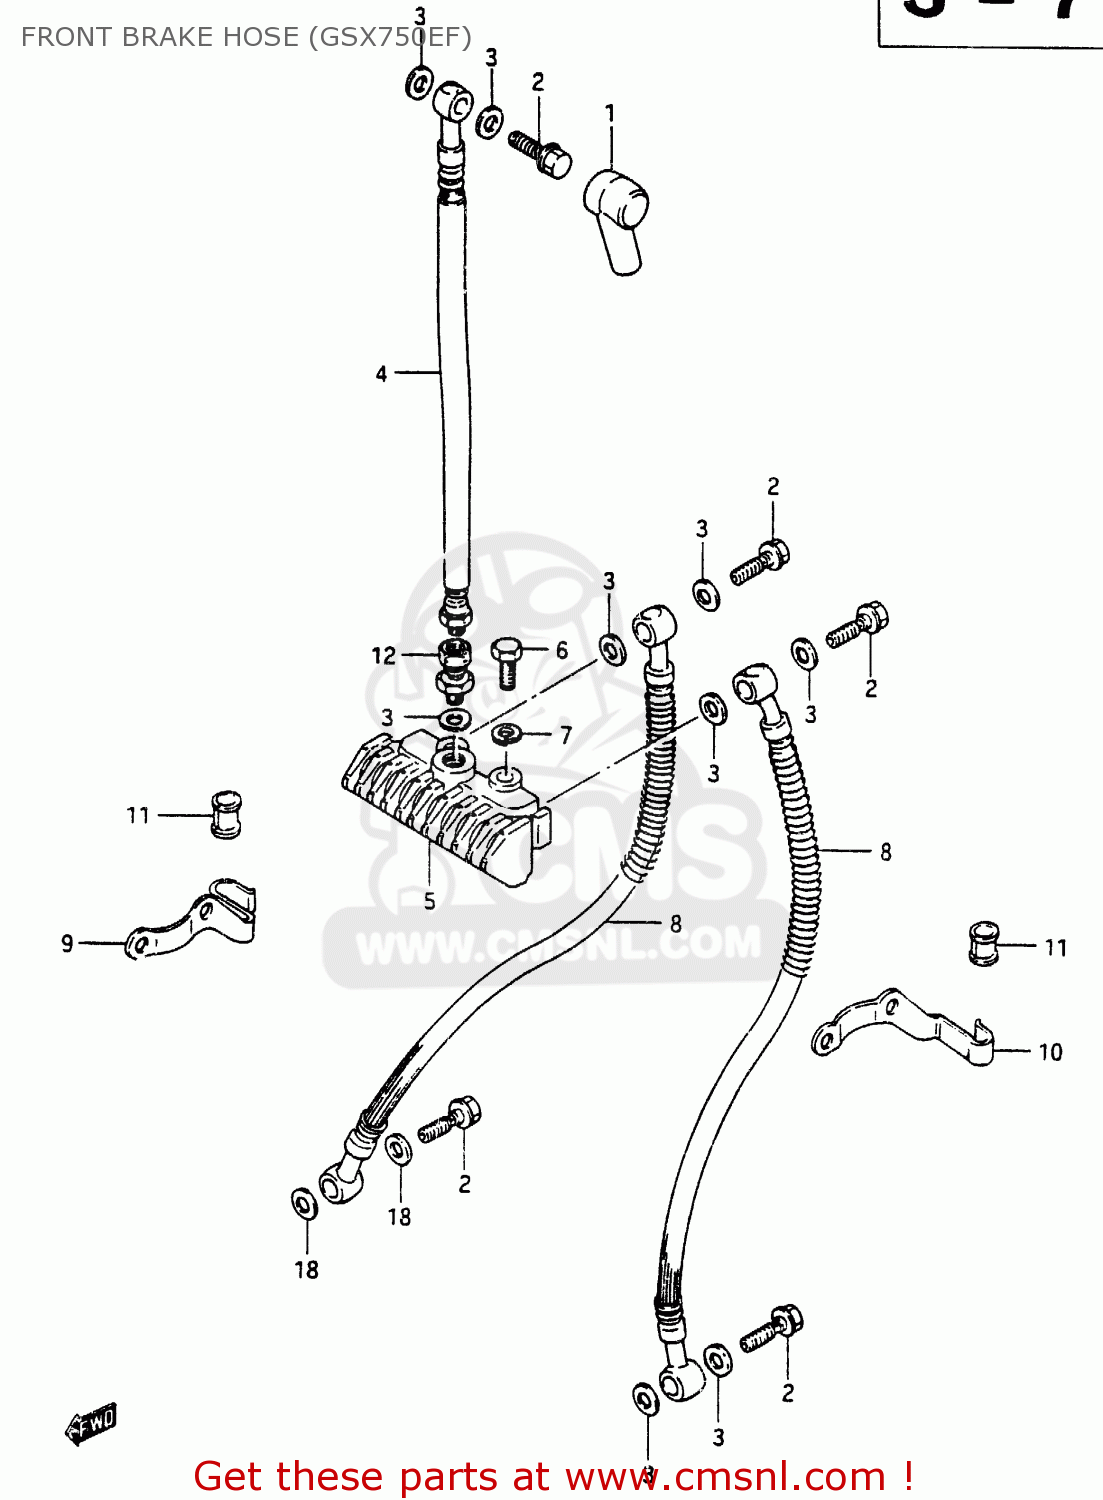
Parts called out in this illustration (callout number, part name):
1	BOOT
2	BOLT UNION
3	WASHER(10X15X1.5)
4	HOSE,FRONT BRAKE NO.1
5	JOINT,BRAKE HOSE
6	BOLT
7	LOCK WASHER
8	HOSE,FRONT BRAKE
9	CLAMP, HOSE RH
10	CLAMP,FRONT BRAKE HOSE
11	BUSH,BRAKE HOSE GUIDE,NO.2
12	ADAPTER,BRAKE HOSE
